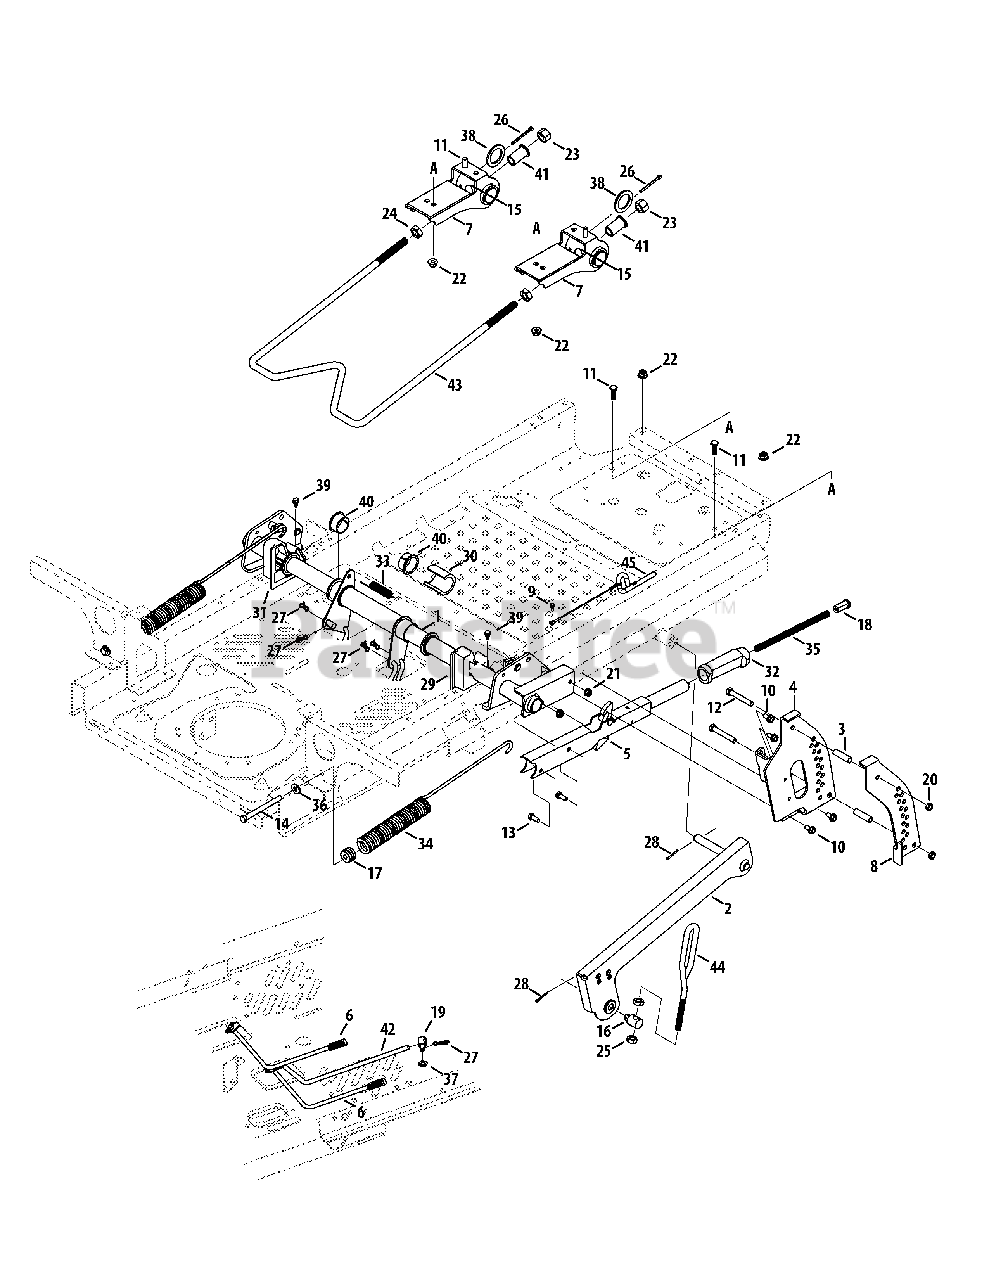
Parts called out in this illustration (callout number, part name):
2	Lift Arm, RH
2	Lift Arm, LH
3	Spacer, .386 x .63 x 1.75
4	Index Bracket Assembly
5	Latch Handle Assembly
6	Brake Rod Assembly
7	Deck Hanger Bracket
8	Outer Index Bracket
9	Screw, #10-16, .50
10	Hex Washer Screw, 5/16-18 x .750
11	Hex Screw, 3/8-16 x 1.00
12	Hex Head Screw, 3/8-16 x 2.50
13	Hex Cap Screw, 5/16-18 x .75
14	Hex Screw, 3/8-16 x 4.25
15	Pivot Pin, 1.25
16	Ferrule, .496 x .528
17	Spring Insert
18	Handle Button
19	Ferrule, 3/8-24 x .375
20	Jam Lock Nut, 3/8-16
21	Flange Lock Nut, 5/16-18
22	Flange Lock Nut, 3/8-16
23	Nylock Nut, 5/8-11
24	Jam Nut, 5/8-11
25	Nut,Hex Nylok 1/2-13
26	Cotter Pin, 3/16 x 2.0
27	Bow-Tie Cotter Pin
28	Cotter Pin 1/8 x 1.25
29	Deck Lift Bracket
30	Spacer, 1.375 Shaft
31	Deck Lift Bracket, LH
32	Grip, Deck Lift Handle
33	Extension Spring, .63 Dia. x 4.95 LG
34	Extension Spring, 1.485 OD x 17.58
35	Spring, Compression, .4 x 8.52
36	Flat Washer, .385 x .870 x .092
37	Washer, .375 x .700 x .030
38	Flat Washer, 1.875 x 1.38 x .097
39	Shoulder Screw, .500 x 1/4-20
40	Flange Bearing, 1.38 x 1.75 x .50
41	Flange Bearing, .875 x .702 x 1.10
42	Brake Rod
43	Deck Hanger Rod, 5/8
44	Lift Adjust Link
45	Lock Rod, .375
